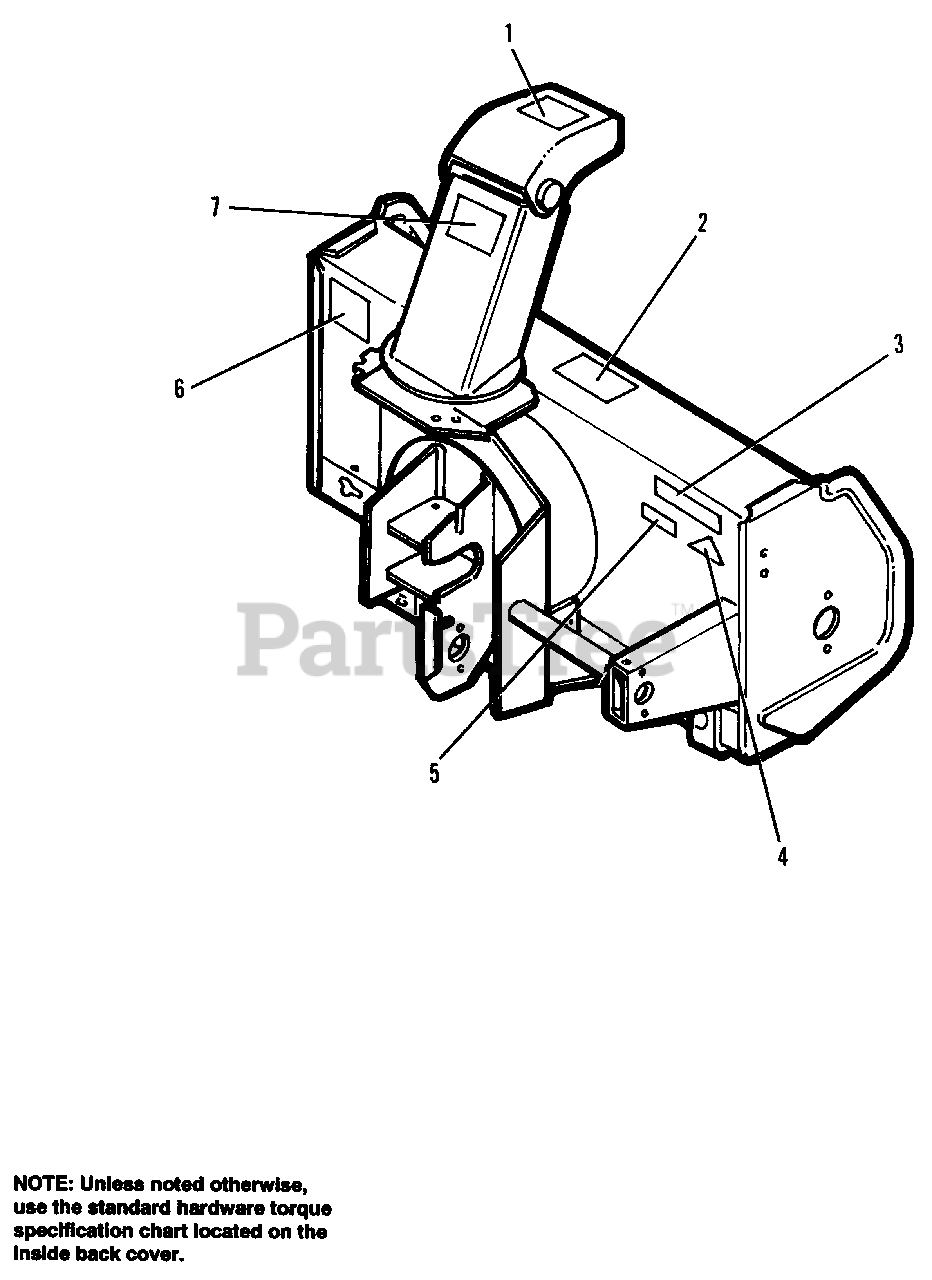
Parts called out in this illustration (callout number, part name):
1	DECAL, Danger (Blower Chute)
2	DECAL, Danger (Auger Blade)
3	DECAL, Caution (Rear Wheel Weights)
4	DECAL, OPEI
5	SERIAL PLATE
6	DECAL, Danger (Drive Belts)
7	DECAL, Danger (Operating Procedures)
